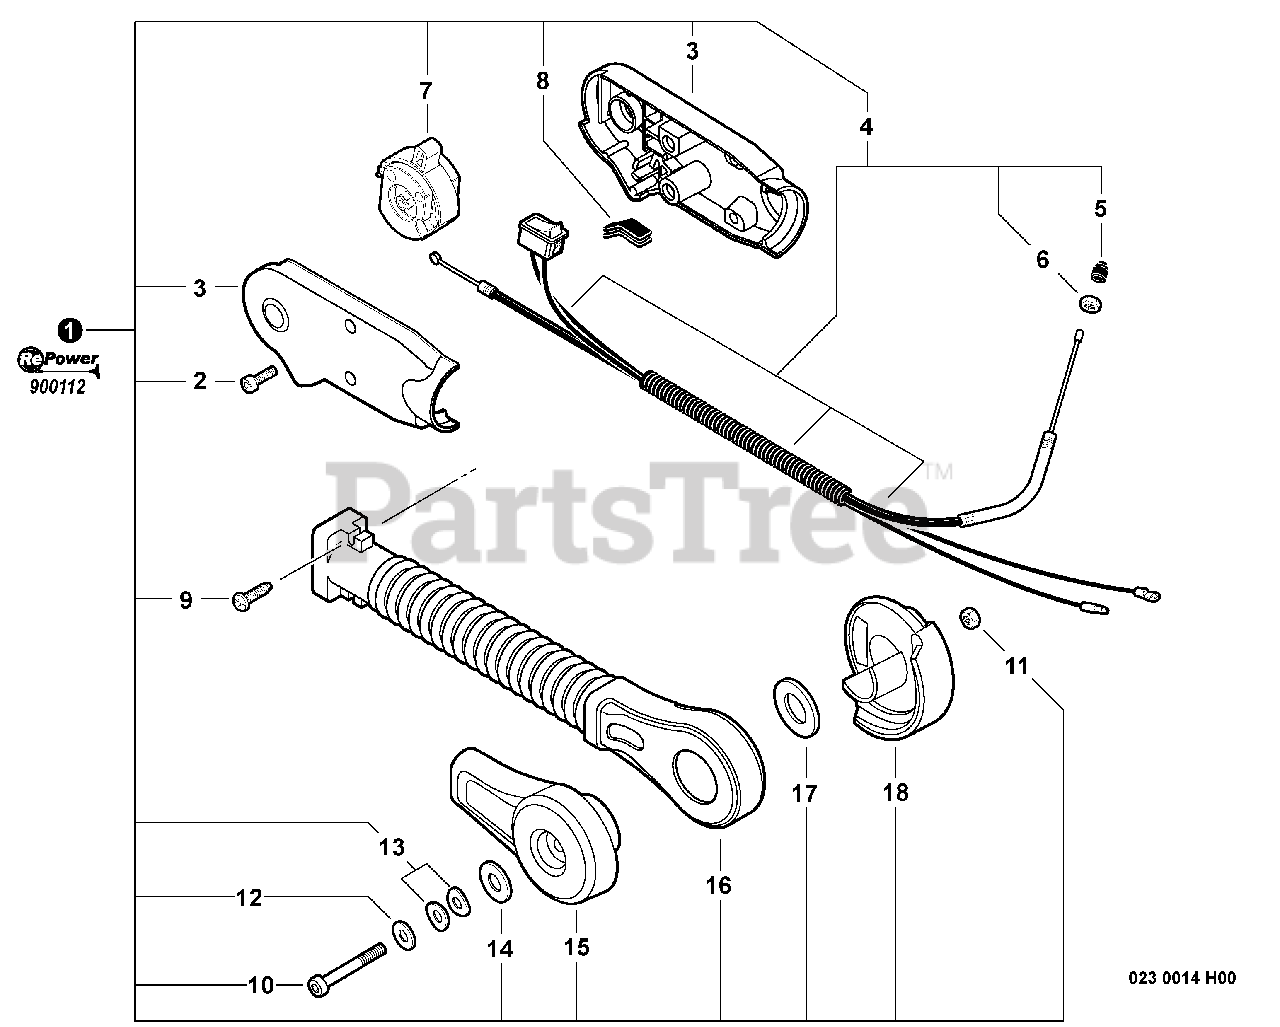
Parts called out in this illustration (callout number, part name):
1	THROTTLE CONTROL KIT - HIP MOUNT
2	BOLT, TORX 5×16
3	GRIP SET, THROTTLE
4	CABLE ASSY, CONTROL
5	CAP, DUST
6	NUT, HEX M6
7	THROTTLE CONTROL ASSY
8	GROMMET
10	BOLT, TORX 6×75
11	NUT, LOCK M6
12	WASHER 6.6×20×1.6
13	WASHER, FRICTION 6.6×14.3
14	WASHER 6.5×15.5×0.6
15	BRACKET, ARM - OUTER
16	ARM, THROTTLE CONTROL
17	WASHER 45
18	BRACKET, ARM - INNER
